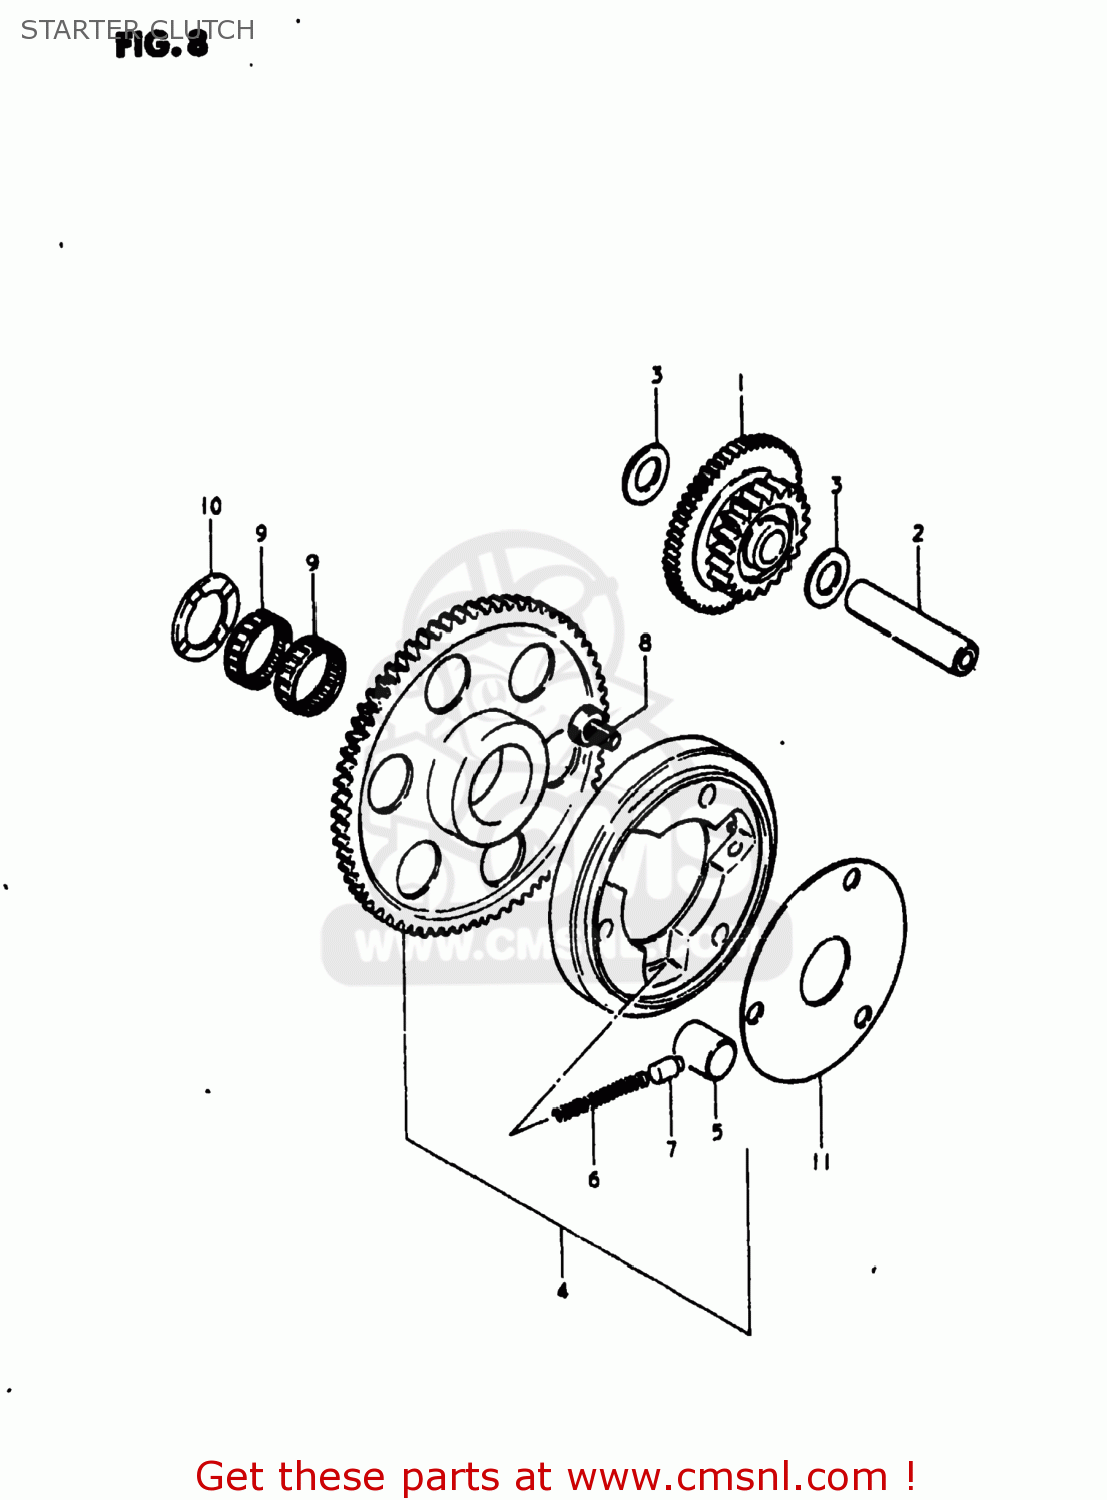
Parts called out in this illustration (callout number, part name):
1	GEAR,STARTER IDLE
2	PIN(7.4X13X56)
3	WASHER(13.3X25X0.85)
4	CLUTCH SET,STARTER
5	ROLLER(15X13)
6	SPRING
7	PIECE,PUSH
8	BOLT
9	BEARING
10	WASHER(25X38X2.5)
11	SHIM,STARTER CLUTCH HUB
